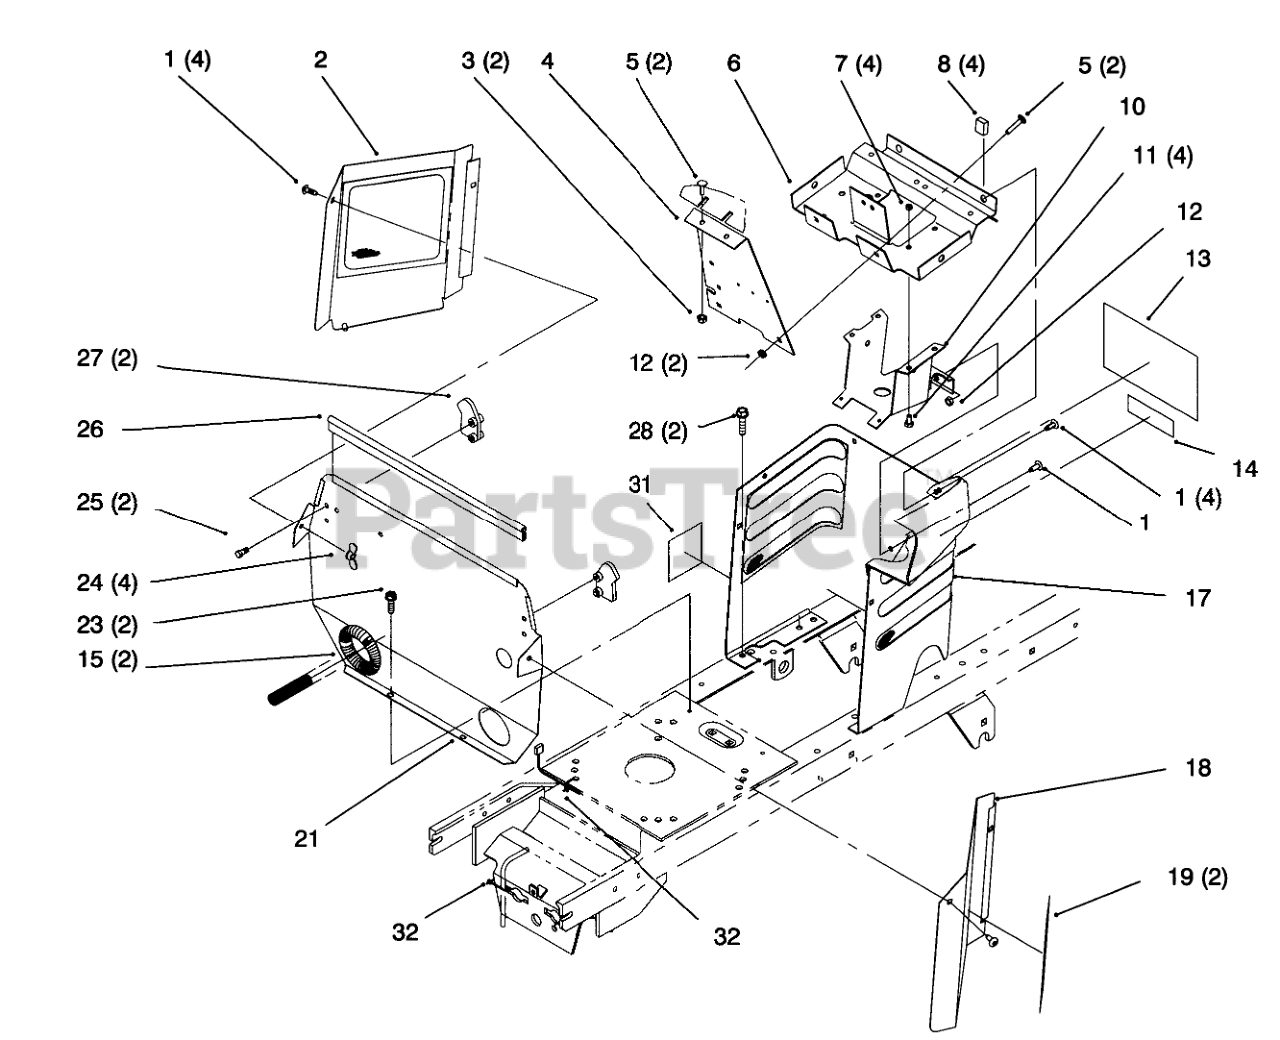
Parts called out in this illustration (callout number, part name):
1	SCREW-HH
2	RH SIDE COVER ASM
3	NUT-KEPS
4	Panel-Support Dash
5	SCREW-CARR
6	SUPPORT-DASH
7	NUT-HEX
8	NUT RETAINER - J TYPE
10	BRACKET-COLUMN, LOWER
11	SCREW-HH
12	NUT-LOCK, NI
13	Decal-Slope/Park Brake (Only On: 72062)
13	Decal-Slope/Park Brake (Only On: 72063, 72103)
13	Decal-Slope/Park Brake (Only On: 72042)
13	Decal-Slope/Park Brake (Only On: 72043)
14	DECAL-INSTRUCTION
15	COVER-SHAFT, DRIVE
17	Hoodstand W/Decals (Only On: 72042)
17	Hoodstand W/Decals (Only On: 72043)
17	Hoodstand W/Decals (Only On: 72062)
17	Hoodstand W/Decals (Only On: 72063, 72103)
18	LH COVER ASM
19	Decal-264-6 (Only On: 72042, 72062)
19	Decal-264-H (Only On: 72043, 72063)
19	Decal-268-H (Only On: 72103)
21	FIREWALL (BLACK)
23	SCREW-HWH
24	NUT-WING
25	SCREW-PLASTITE
26	TRIM-SEAL, FIREWALL
27	LATCH-HOOD
28	SCREW-HWHTF
31	Decal-Noise (Only On: 72062, 72063, 72103)
32	TIE-CABLE
